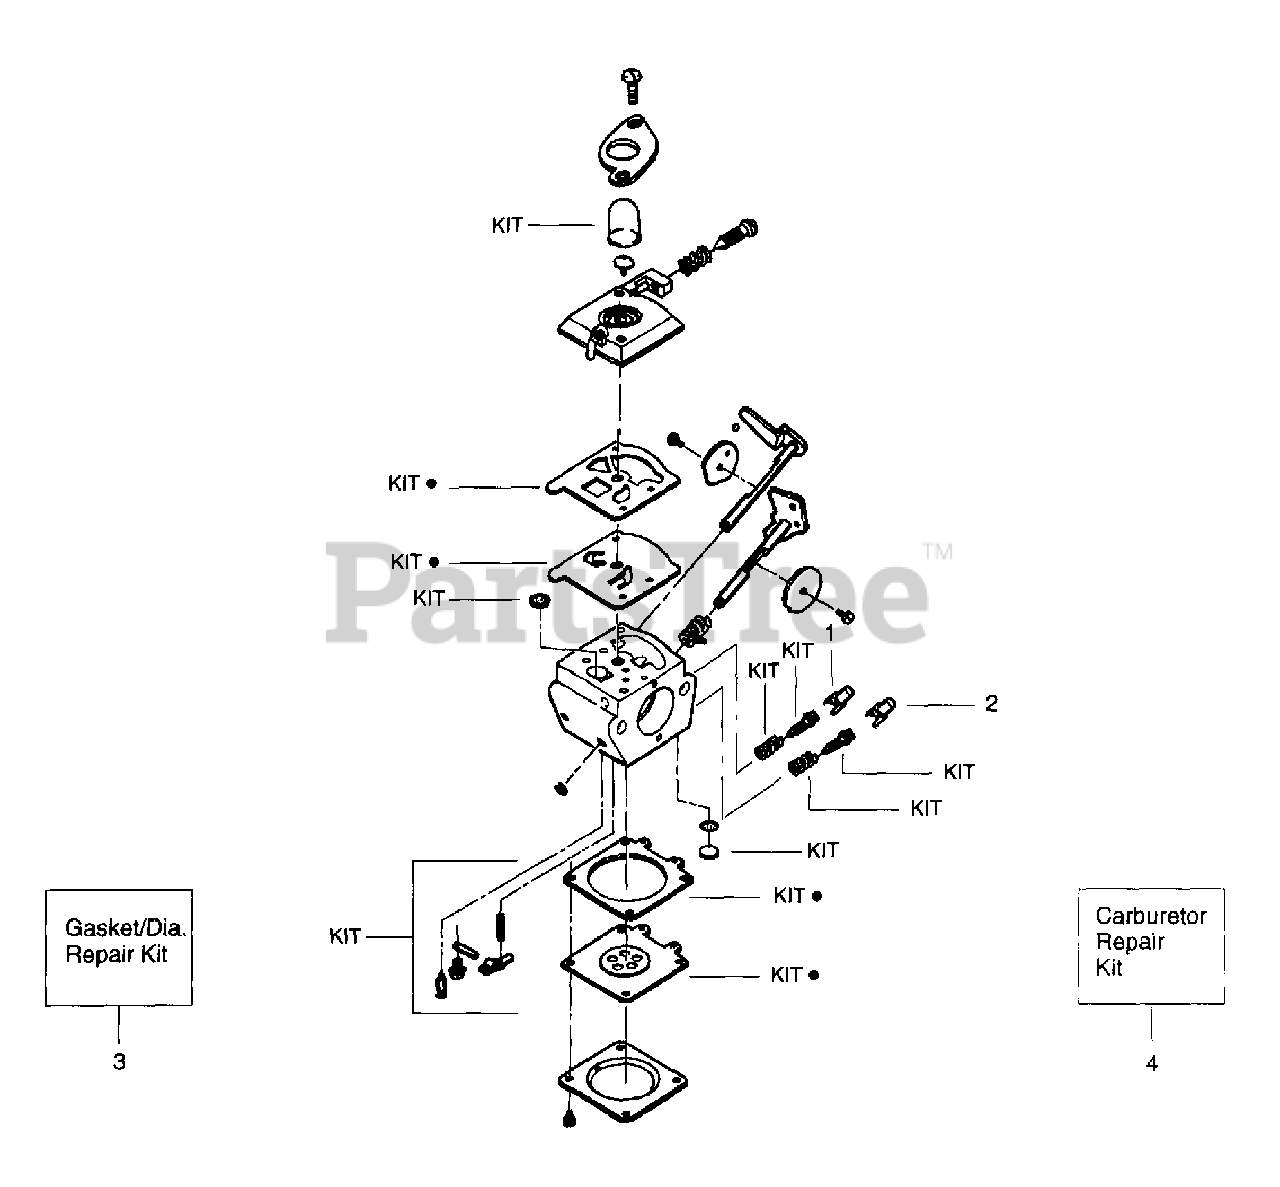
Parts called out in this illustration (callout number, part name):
1	Limiter Cap-Low
2	Limiter Cap-High
3	Gasket/Diaphragm Kit
4	Carburetor Repair Kit
